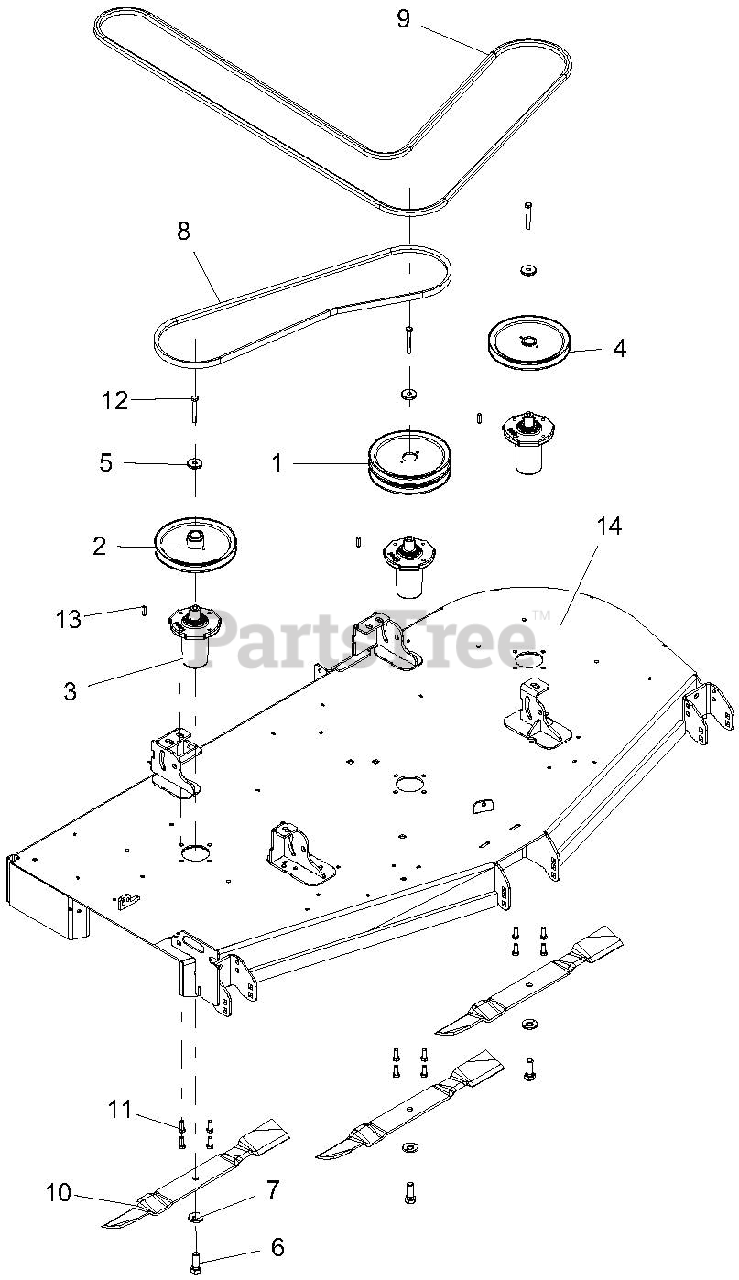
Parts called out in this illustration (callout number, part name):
1	SHEAVE-DOUBLE 1.00"ID X 8.25"OD-BLACK
2	SHEAVE, SINGLE 1.00" ID X 8.25" OD-BLACK
3	SERVICE, ASM SPINDLE- DUCTILE
4	SHEAVE-SINGLE 1.00" X 8.25" OD-BLACK
5	RETAINER, SHEAVE SPINDLE
6	BLT, HEX .62-18X1.75 GR8 YWZC
7	WSHR, BLVL .63X1.625X.14
8	V-BELT, B-COGGED
9	HEX BELT, BB-WRAPED
10	BLADE, MOWER -72" MULCH
11	BLT-HEX .38-16X1.00 GR5 YWZC EP30
12	BLT-HEX .38-16X2.75 GR8 YWZC
13	KEY-SQ .250X.250X1.00 RC 40-50
14	72" SIDE DISCH DECK W/SAFETY DECALS
